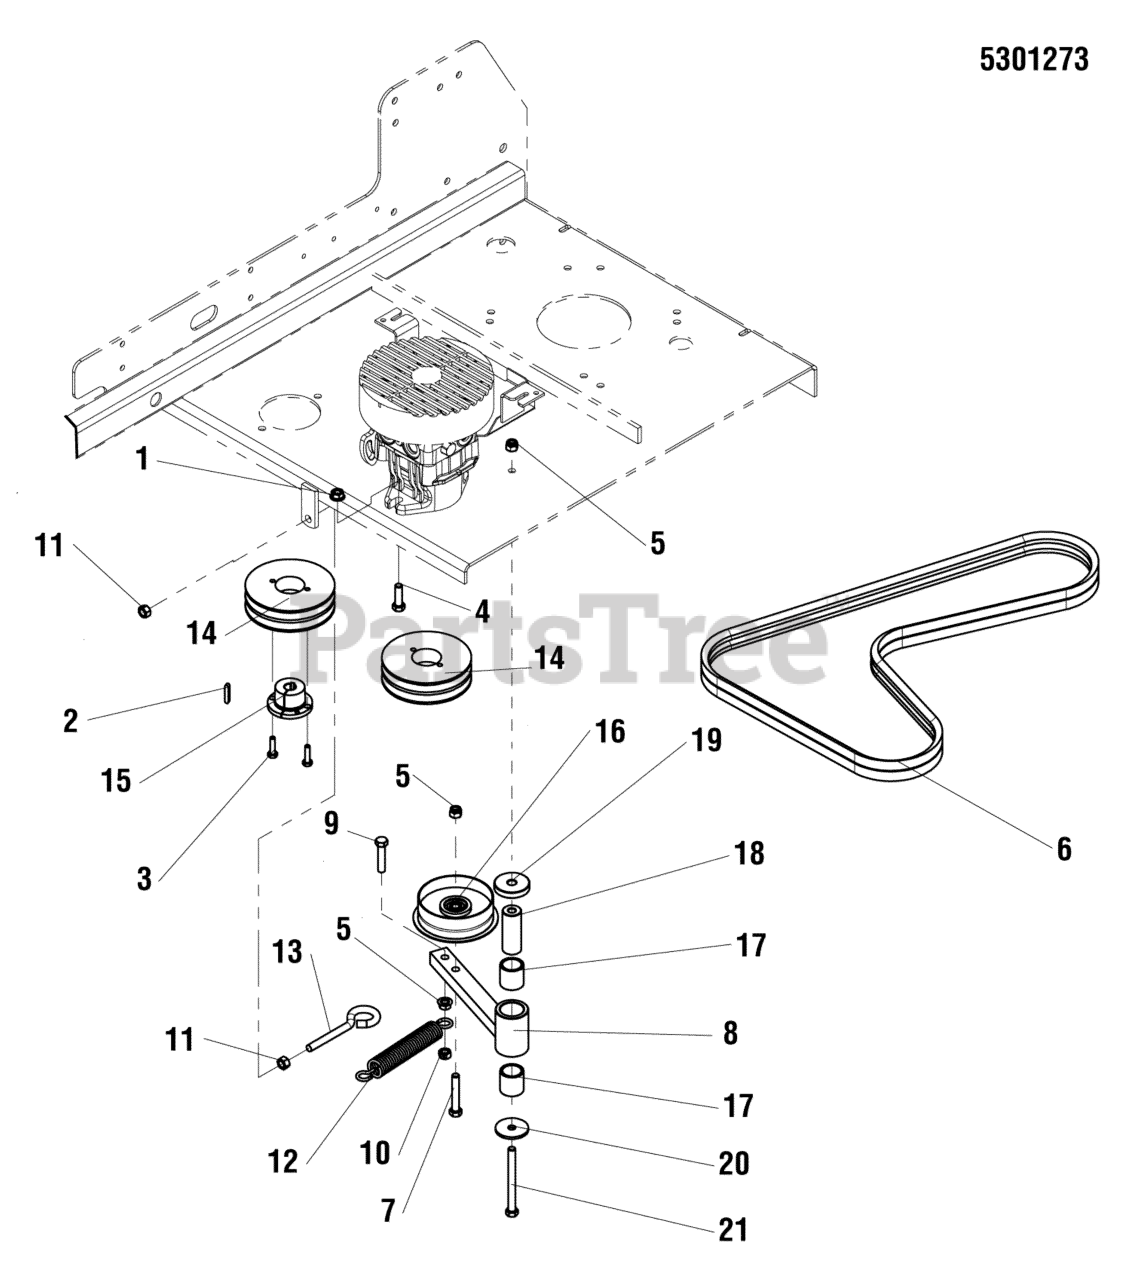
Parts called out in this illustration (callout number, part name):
1	NUT, 3/8-16 HEX SERRATED FLANGE
2	KEY, 5MM SQ. W/ RADIUS
3	BOLT, 1/4-20 X 1" GD5 CZ
4	BOLT, 3/8-16 X 1-1/4" GD5 CZ
5	NUT, 3/8-16 HEX NYLOCK FLANGE
6	BELT, BANDED A-SEC,64.76EL,POLY,RAW EDGE
7	BOLT, 3/8-16 X 2-1/4" GD5 CZ
8	WELD, ARM, PUMP DRIVE IDLER - BLK
9	BOLT, 3/8-16 X 1-3/4" GD5 CZ
10	NUT, 3/8-16 HEX SIDE LOCK
11	NUT, 3/8-16 HEX
12	SPRING, EXTENSION, SWIVEL END
13	EYE BOLT, 3/8-16 X 4-1/4, 1 EYE
14	PULLEY, PUMP DRIVE
15	BUSHING, TAPERED HUB
16	PULLEY, IDLER, SINGLE FLANGE
17	BUSHING, BRASS, 1.25X1X1.25
18	SPACER, .39 X 1.000 X 2.55, SS
19	SPACER, .45 X 1.88 X .38
20	WASHER, .41 X 1.75 X .14
21	BOLT, 3/8-16 X 4" GD5 CZ
